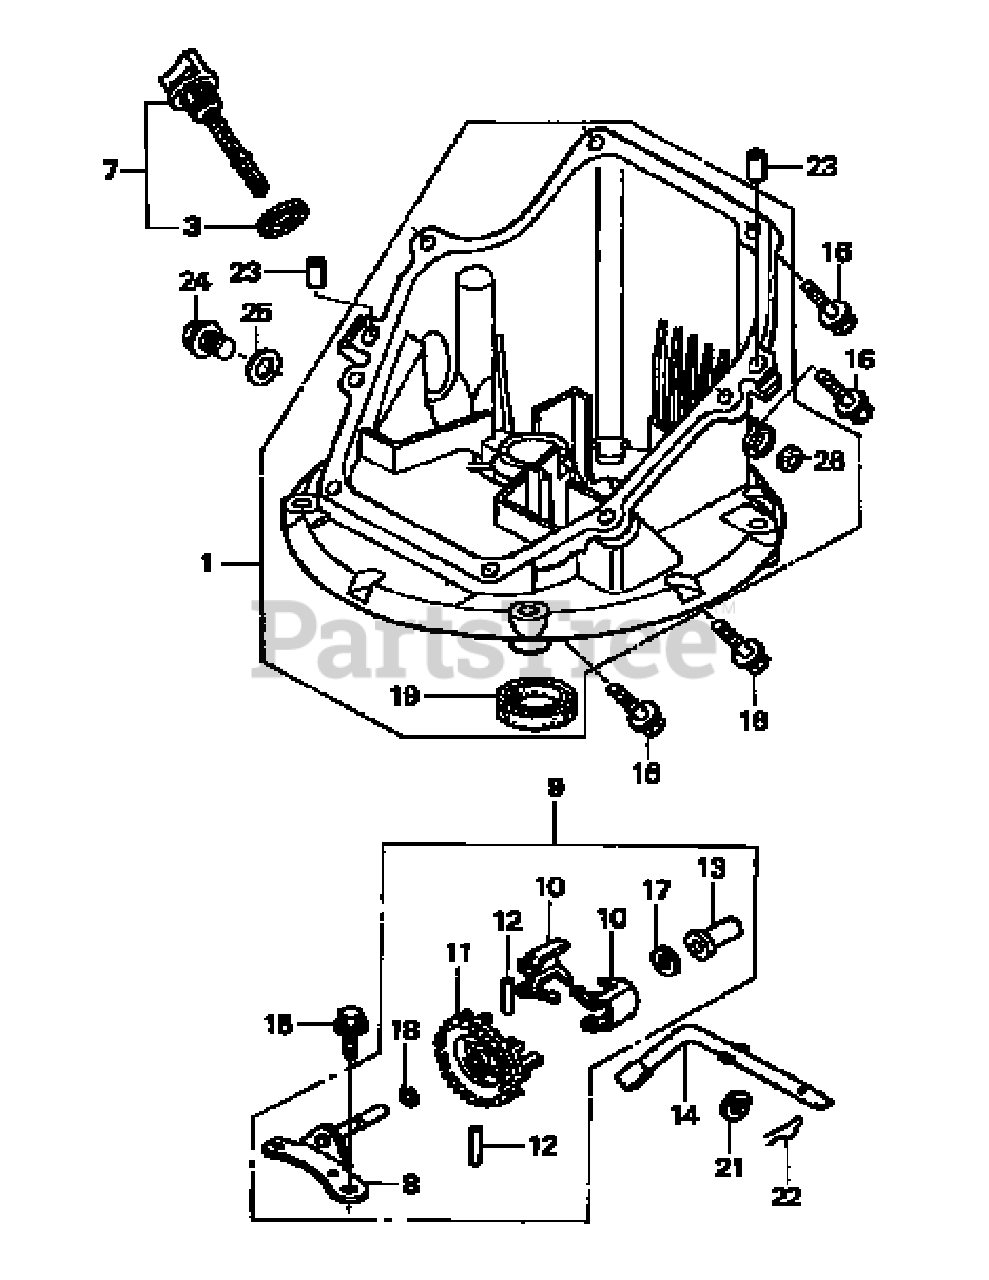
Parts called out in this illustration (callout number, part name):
1	Oil Pan Assy.
3	Oil Filler Cap Gasket
7	Oil Dipstick
8	Governor Holder Shaft
9	Governor Assy.
10	Governor Weight
11	Governor Weight Holder
12	Governor Weight Pin
13	Governor Slider
14	Governor Arm Shaft
15	Flange Bolt (6x14)
16	Flange Bolt (6x25)
17	Thrust Washer (6mm)
18	Governor Holder Clip
19	Oil Seal (28x41.25x6)
21	Plain Washer (6mm)
22	Lock Pin (8mm)
23	Dowel Pin (8x20)
24	Drain Plug Bolt
25	Drain Plug Washer
